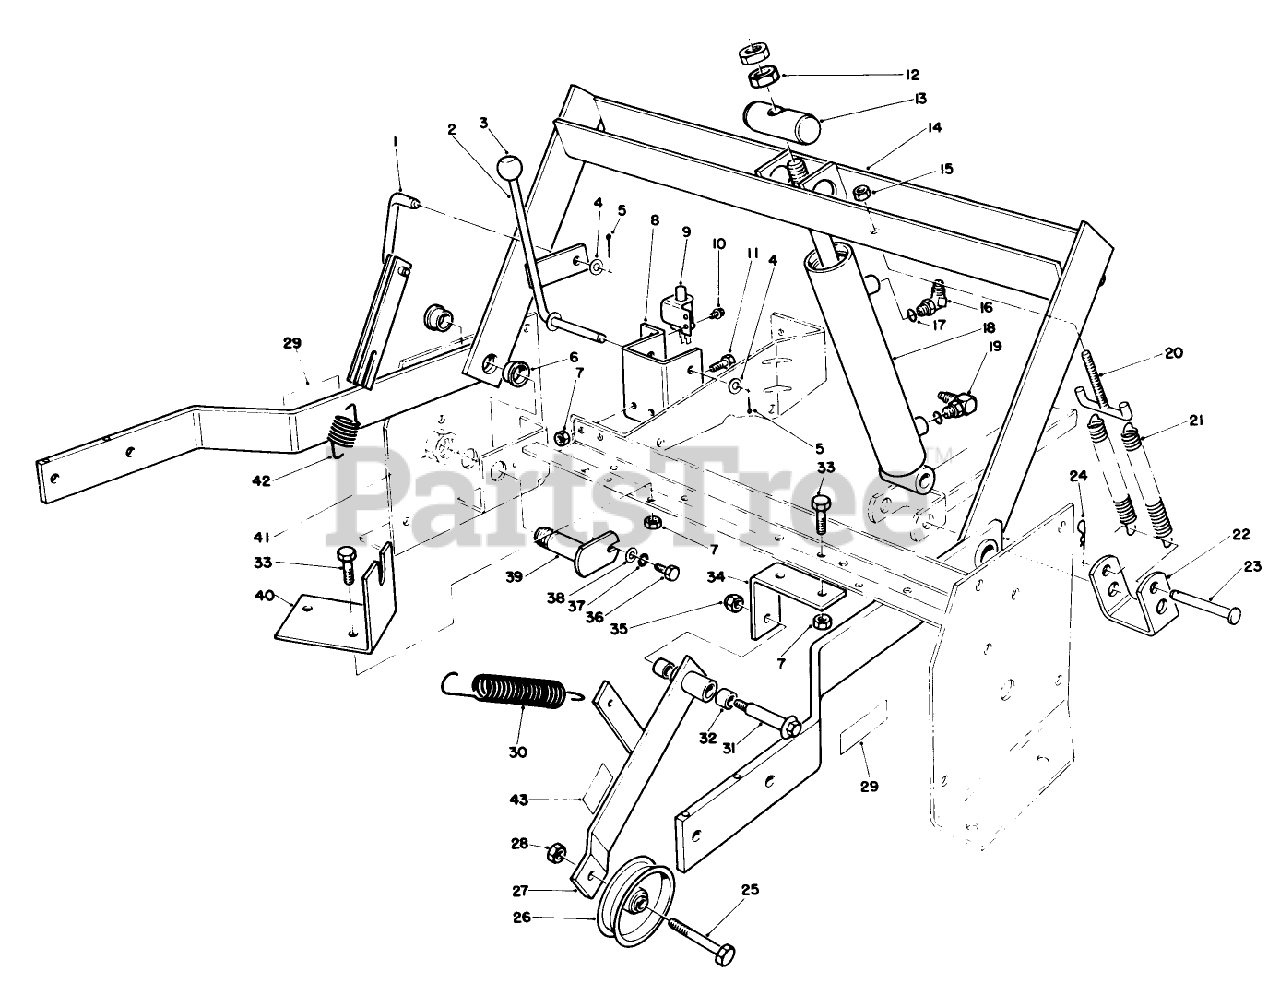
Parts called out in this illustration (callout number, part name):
1	Link-Parking Brake
2	Brake Lever
4	WASHER-FLAT
5	PIN-COTTER
6	BEARING-FLANGE
7	NUT-LOCK, NI
8	Bracket-Parking Brake
9	SWITCH-BRAKE, PARKING
10	SCREW-TAPTITE
11	SCREW-HH
12	NUT-JAM
13	CYL.PIVOT PIN
14	Frame-Lift(Incl Ref. #6)
15	Nut
16	FITTING-45 DEG
17	O-RING
18	CYLINDER - LIFT
19	FITTING-ELBOW, 90
20	T-HOOK W A
21	SPRING_EXTENSION
22	SPRING BRACKET
23	PIN-CLEVIS
24	PIN-HAIR
25	SCREW-HH
26	PULLEY-IDLER
27	Idler Lever (Incl. Ref. #43)
28	NUT-LOCK, NI
29	WARNING DECAL
30	IDLER EXT SPRING
31	BOLT-WHEEL
32	BUSHING
33	SCREW-HH
34	JACKSHFT IDLR BRKT
35	NUT-LOCK
36	SCREW-HH
37	WASHER-LOCK
38	WASHER-FLAT
39	Pin-Pivat
40	TRACT CABLE BRKT
41	NUT-LOCK, NI
42	PARK BRAKE SPRING
43	DECAL-WARNING
